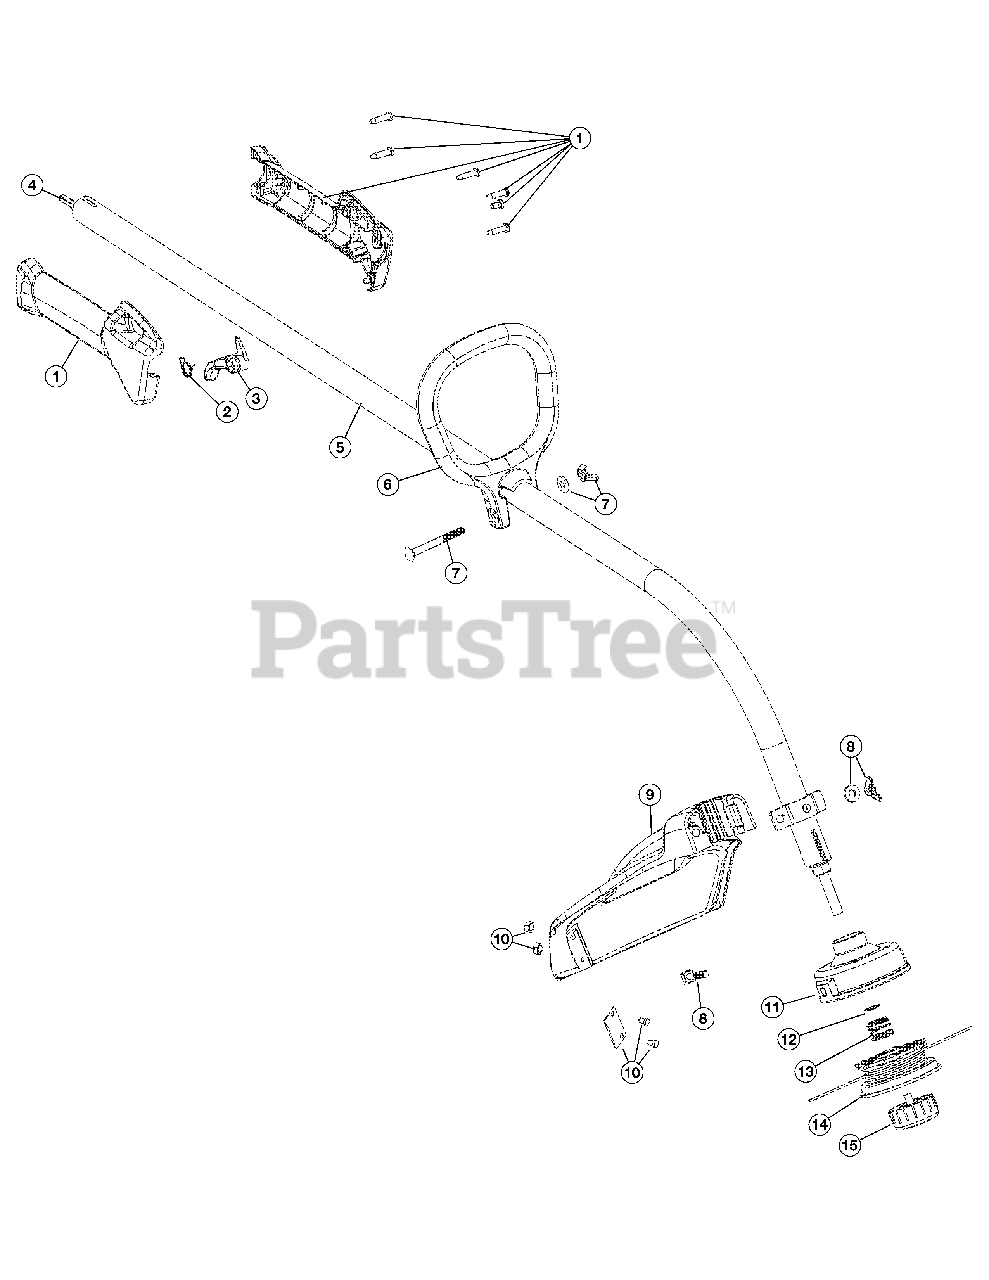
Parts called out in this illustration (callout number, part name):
1	Throttle Housing Assembly (includes 2 & 3)
2	Throttle Trigger Spring
3	Throttle Trigger
4	Flexible Drive Shaft
5	Drive Shaft Housing (includes 4 & 12)
6	D-Handle Assembly (includes 7)
7	D-Handle Hardware
8	Guard Mounting Hardware
9	Guard (includes 10)
10	Blade Assembly
11	Outer Reel (includes 12)
12	Retainer
14	Inner Reel (line not included)
15	Bump Knob
